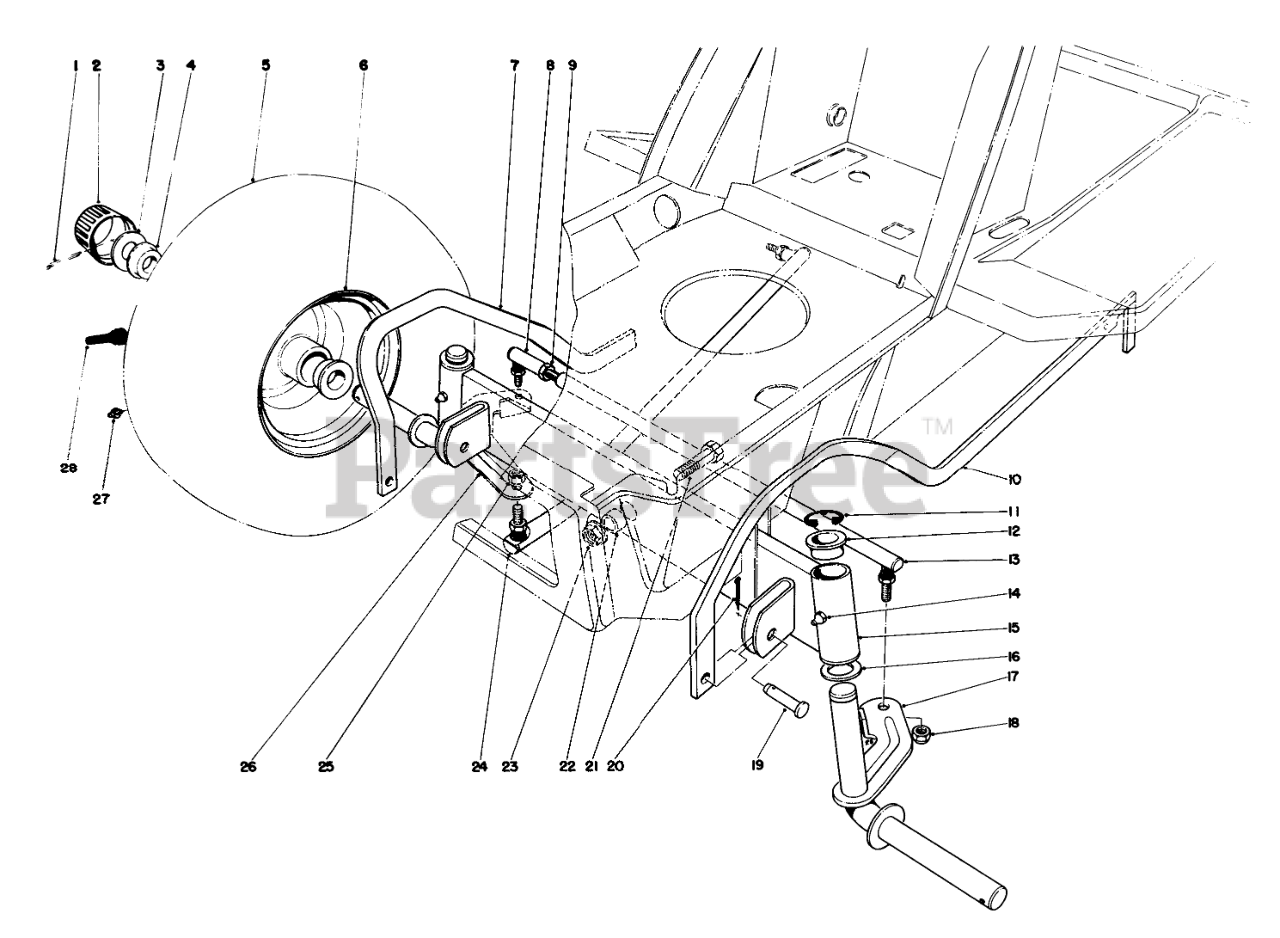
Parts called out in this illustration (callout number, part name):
1	PIN-COTTER
2	CAP-HUB
3	WASHER-PLAIN
4	Bearing
5	TIRE-FRONT
6	FRONT WHEEL
7	RH DECK PARALLEL LINK R
8	JOINT-BALL
9	NUT-JAM
10	LH DECK PARALEL LNKR
11	E-RING
12	BEARING-FLANGE
13	Tie Rod, Steering (Incl. Ref. #8 & 9)
14	GREASE FITTING
15	Axle-Front (Incl. Ref. #12
16	WASHER-THRUST
17	Spindle L.H.
18	NUT-LOCK, NI
19	PIN-CLEVIS
20	PIN-COTTER
21	SCREW-HH
22	SPACER-AXLE, FRONT
23	NUT-HF
24	STEERING ARM B
25	NUT-HEX
26	SPINDLE WA RH B
27	FITTING-GREASE
28	STEM-VALVE
